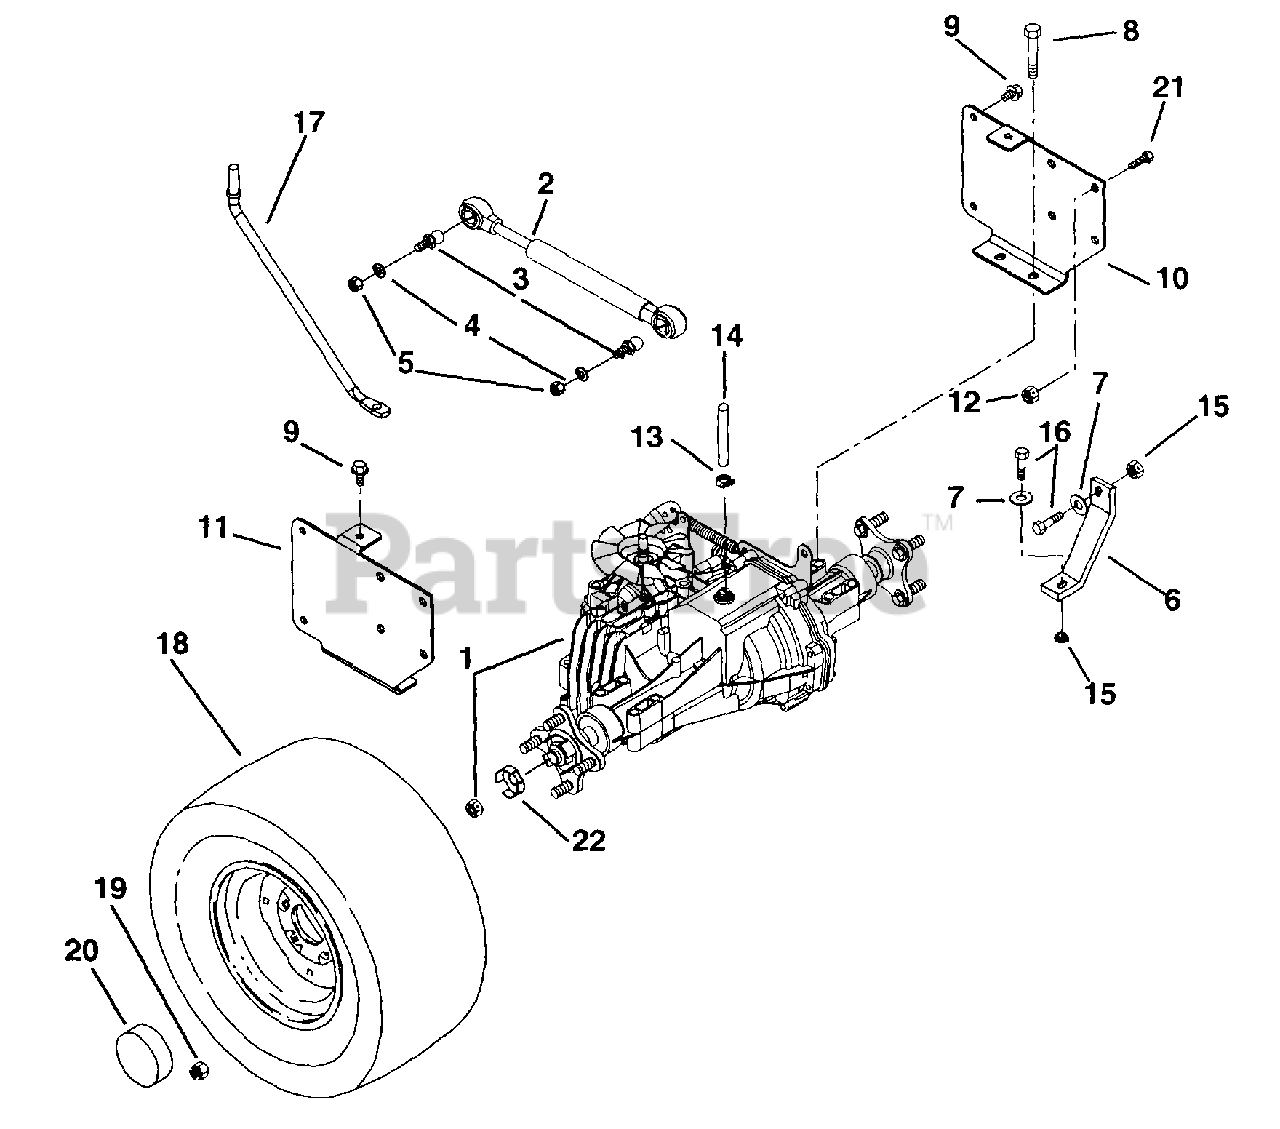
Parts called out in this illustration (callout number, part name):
1	Transaxle-Hydro Gear
2	Damper-Hydraulic
3	Stud-Ball
4	Washer-Lock .312 x .097
5	Nut-Hex .31-18
6	Brace-Transaxle
7	Washer .344 x .688 x .065
8	Bolt-Hex .38-16 x 3.00 Grade 5
9	Screw-Tapping .375-16 x .50
10	Mount-Axle Left Hand
11	Mount-Axle Right Hand
12	Nut-Lock Center .38-16
13	Hose Clamp
14	Hose-Vent .75 O.D. x 12.00
15	Nut-Locking-Center .31-18
16	Bolt-Hex .31-18 x .75 Grade 5
17	Rod-Dump Valve
18	Tire/Wheel Assembly 10.50 x 23
19	Nut-Lug .437-20
20	Rear Hub Cap
21	Bolt-Hex .38-16 x .75 Grade 5
22	Spindle Cup
